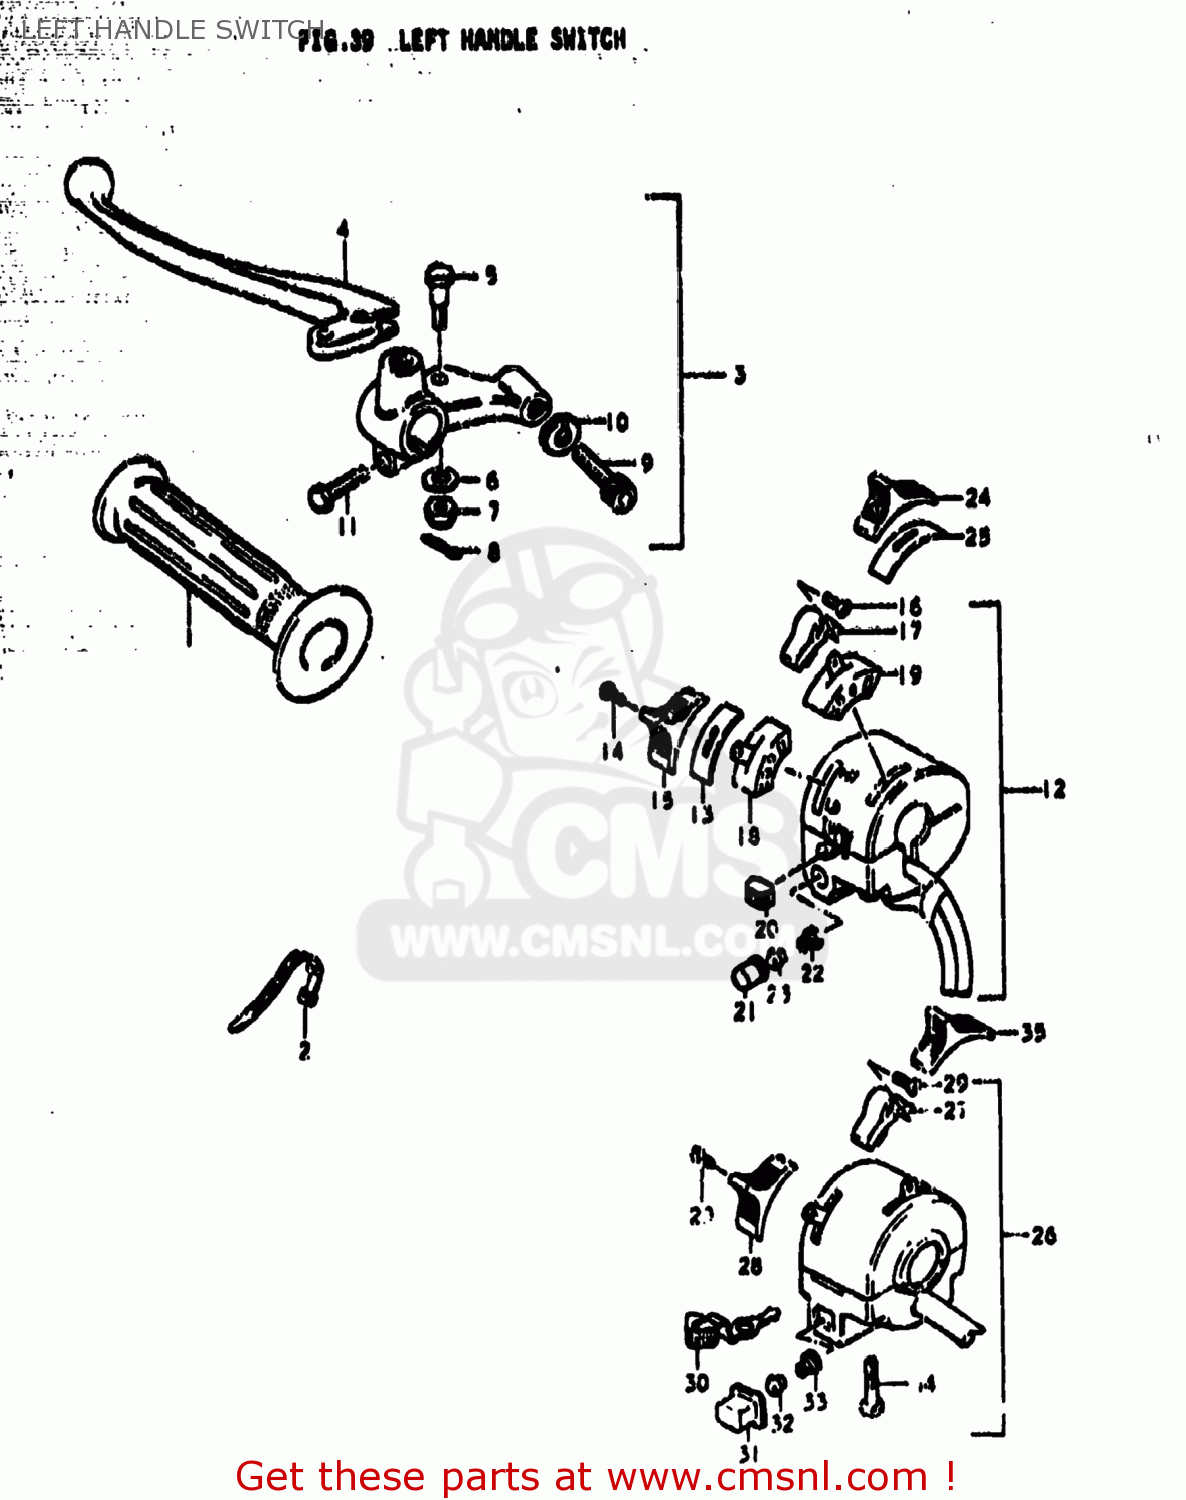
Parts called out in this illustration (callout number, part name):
1	GRIP,L
2	CLAMP(L:120)
3	LEVER ASSEMBLY
4	LEVER,CLUTCH
5	BOLT,LEVER
6	LOCK WASHER
7	NUT 6MM
8	COTTER PIN
9	ADJUSTER,CABLE
10	NUT,CABLE ADJUSTER
11	BOLT
12	SWITCH ASSEMBLY,HANDLE,LEFT
13	PLATE,DIMMER KNOB
14	SCREW, DIMMER
15	KNOB,HANDLE SWITCH,UPPER
16	SCREW
17	KNOB
18	SLIDING BLOCK, DIMMER SWITCH
20	KNOB,HANDLE SWITCH
21	BUTTON, HORN
22	SPRING,BUTTON
23	PLATE,HORN BUTTON
24	KNOB,HANDLE SWITCH
25	PLATE,LIGHTING KNOB
26	SWITCH ASSEMBLY,HANDLE,LEFT
27	KNOB,STOP
28	KNOB,DIMMER SWITCH
29	SCREW
30	KNOB,TURNSIGNAL
31	BUTTON,HORN
32	CONTACT
33	SPRING
34	SCREW
35	KNOB,LIGHTING SWITCH
